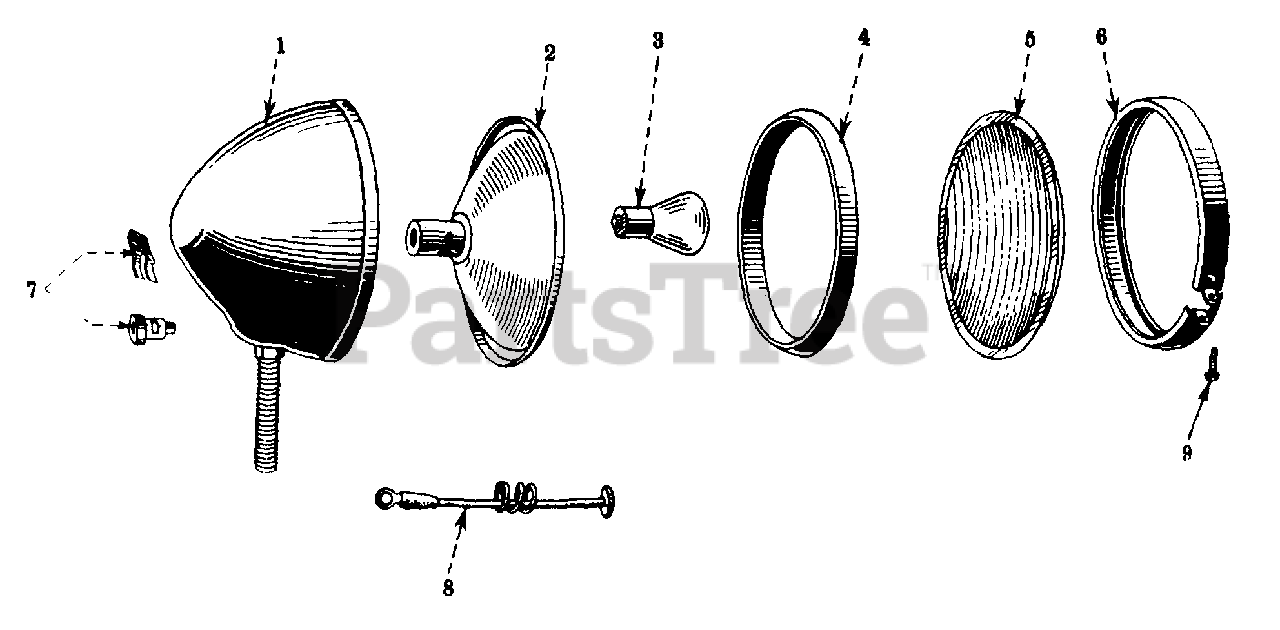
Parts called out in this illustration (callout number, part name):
1	BODY DISCONTINUED FOR SERVICE
2	REFLECTOR
3	LAMP, NO. 1133
7	PACKAGE, TERMINAL PLATE ASSY.
9	SCREW, MOULDING
